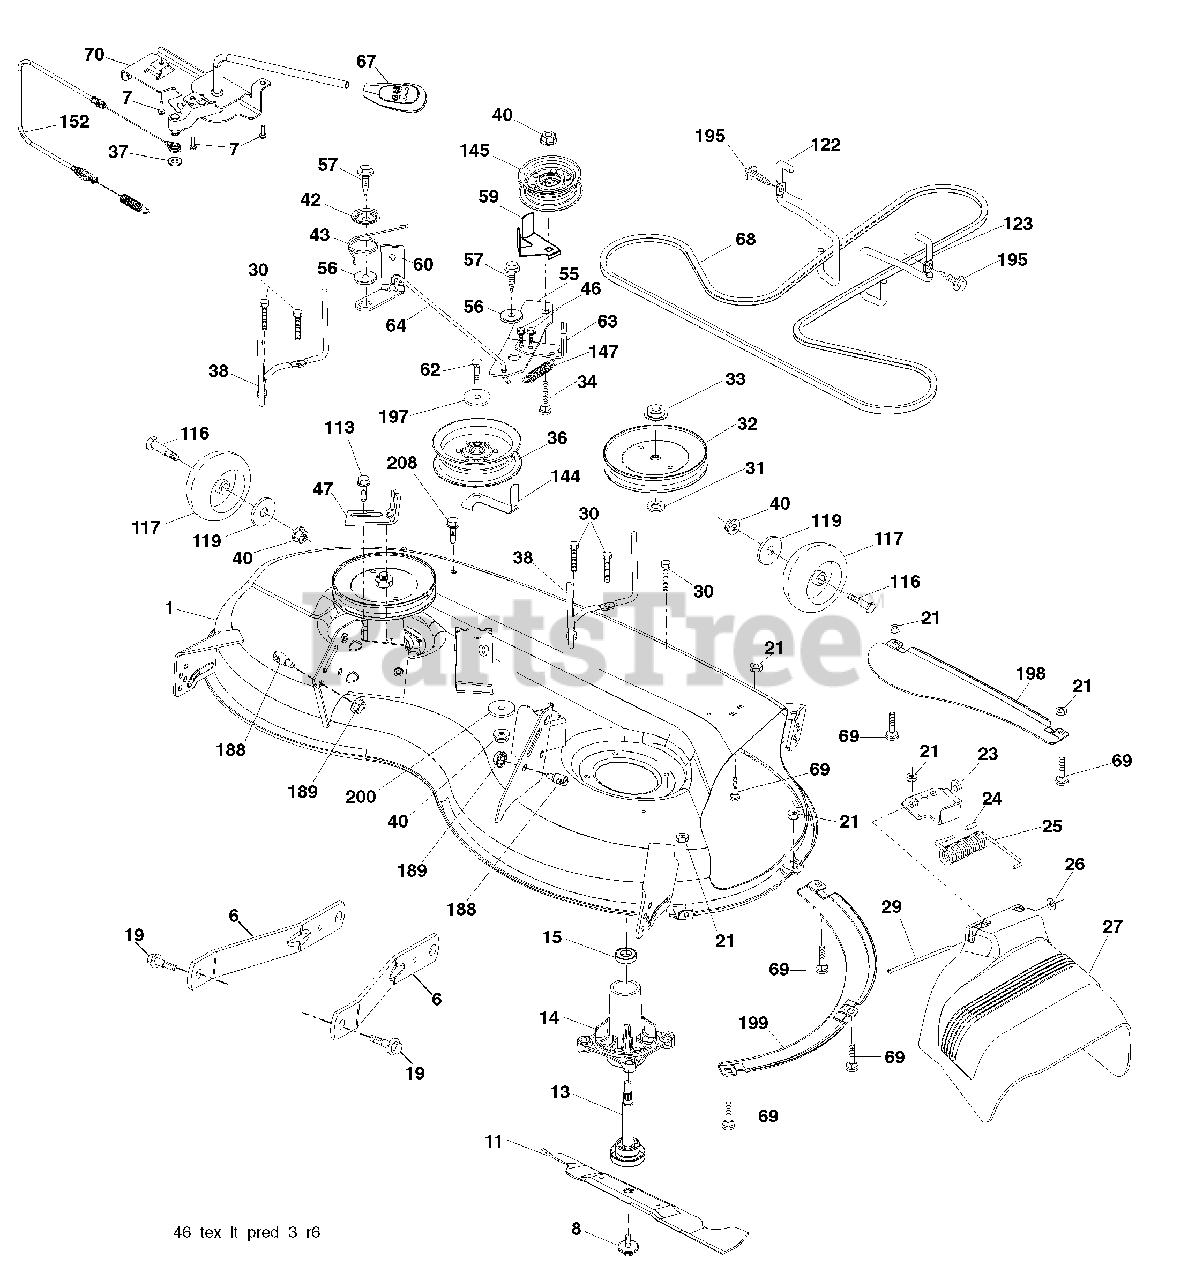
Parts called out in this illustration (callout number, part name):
1	Mower Housing
2	Cover Mandrel RH
3	Cover Mandrel LH
6	Arm Suspension
7	Screw 10 x 3/4 Single Hex
8	Bolt/Washer asm 7/16-20 unf
11	Blade Mower
13	Shaft Assembly, Mandrel
14	Housing, Mandrel
15	Bearing, Ball, Mandrel
19	Bolt, Shoulder
21	Nut
23	Bracket, Deflector
24	Cap, Sleeve
25	Spring, Torsion, Deflector
26	Nut, Push
27	Shield, Deflector
29	Rod, Hinge
30	Screw Thdrol Rolling Wsh Hd
31	Washer, Spacer
32	Pulley, Mandrel
33	Nut, Toplock, Flanged
34	Bolt Carr Sh. 3/8-16 x 1-1/2 Gr. 5
36	Pulley, Idler, Flat
37	Washer 13/32 x 13/16 x 16 Ga.
38	Keeper Belt LH Mandrel
40	Nut, Lock Flg. 3/8-16 unc
42	Spring Torsion Brake
43	Spring Torsion Retainer
46	Screw
47	Bracket Clutch Cable
55	Arm, Idler
56	Spacer, Retainer
57	Screw Hexwsh Thd 3/8-16 x 1
59	Guard, Tuv Idler (94)
60	Arm Brake Mower LH
62	Bolt 3/8-16 unc x 2-1/4 Gr. 5
63	Arm Brake Mower
64	Linkage Brake
67	Handle, Clutch Cable
68	V-Belt
69	Bolt
70	Clutch Asm.
113	Screw 5/16-18
116	Bolt, Shoulder
117	Wheel, Gauge
118	Nut Centerlock 3/8-16 unc
119	Washer 13/32 x 1-1/4 x 12 Ga.
122	Keeper Belt Eng. LH
123	Keeper Belt Eng. RH
144	Keeper Belt
145	Pulley Idler
147	Spring Return
149	Retainer Spring
152	Cable Clutch Manual w/Spr.
188	Stud Fastener
189	Nut Lock Hex Flange
195	Screw 3/8-16 x 3/4
197	Washer 13/32 x 13/16 x 12 Ga.
198	Baffle Center Front
199	Baffle Front RH
200	Washer 13/32 x 2 x 10 Ga.
200	Mandrel Assembly
200	Replacement Mower, Complete
